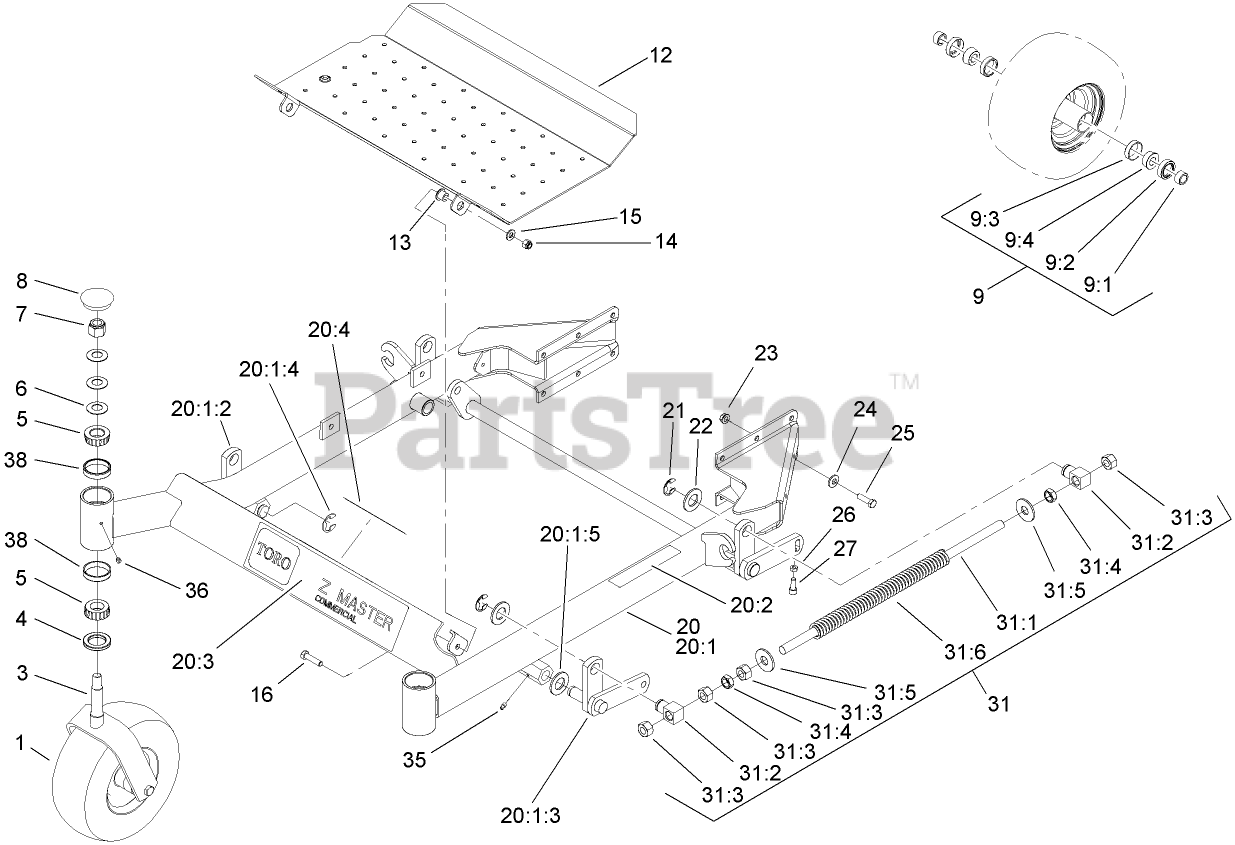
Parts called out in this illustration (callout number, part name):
1	SEMI PNUEMATIC WHEEL ASM
3	CASTER
4	SEAL-GREASE
5	BEARING-CONE, TAPERED
6	WASHER-BELLVILLE
7	NUT-LOCK, NI
8	CAP-GREASE
9	CASTER WHEEL BEARING KIT
9:1	SPACER-BEARING
9:2	SEAL-BEARING
9:3	BEARING-CUP
9:4	BEARING-CONE, TAPER
12	FLOOR PAN
13	BUSHING-FLANGE
14	NUT-LOCK, NI
15	WASHER-FLAT
16	SCREW-HH
20	FRONT FRAME ASM
20:1	FRAME-FRONT
20:1:2	RH LIFT ARM ASM
20:1:3	LH LIFT ARM ASM
20:1:4	RING-RETAINING, EXT
20:1:5	WASHER-FLAT
20:2	DECAL-WARNING
20:4	DECAL-WARNING
21	RING-RETAINING, EXT
22	WASHER-FLAT
23	NUT-HHF, WHIZ
24	WASHER-BELLEVILLE
25	SCREW-HH
26	NUT-JAM
27	SCREW-HSH
31	FRONT FRAME SPRING ASM
31:1	ROD-LIFT, DECK
31:2	SWIVEL-DECK MOUNT, REAR
31:3	NUT-HEX
31:4	NUT-JAM
31:5	WASHER-FLAT
31:6	SPRING-SUPPORT, DECK
35	FITTING-GREASE
38	BEARING-CUP, TAPERED
